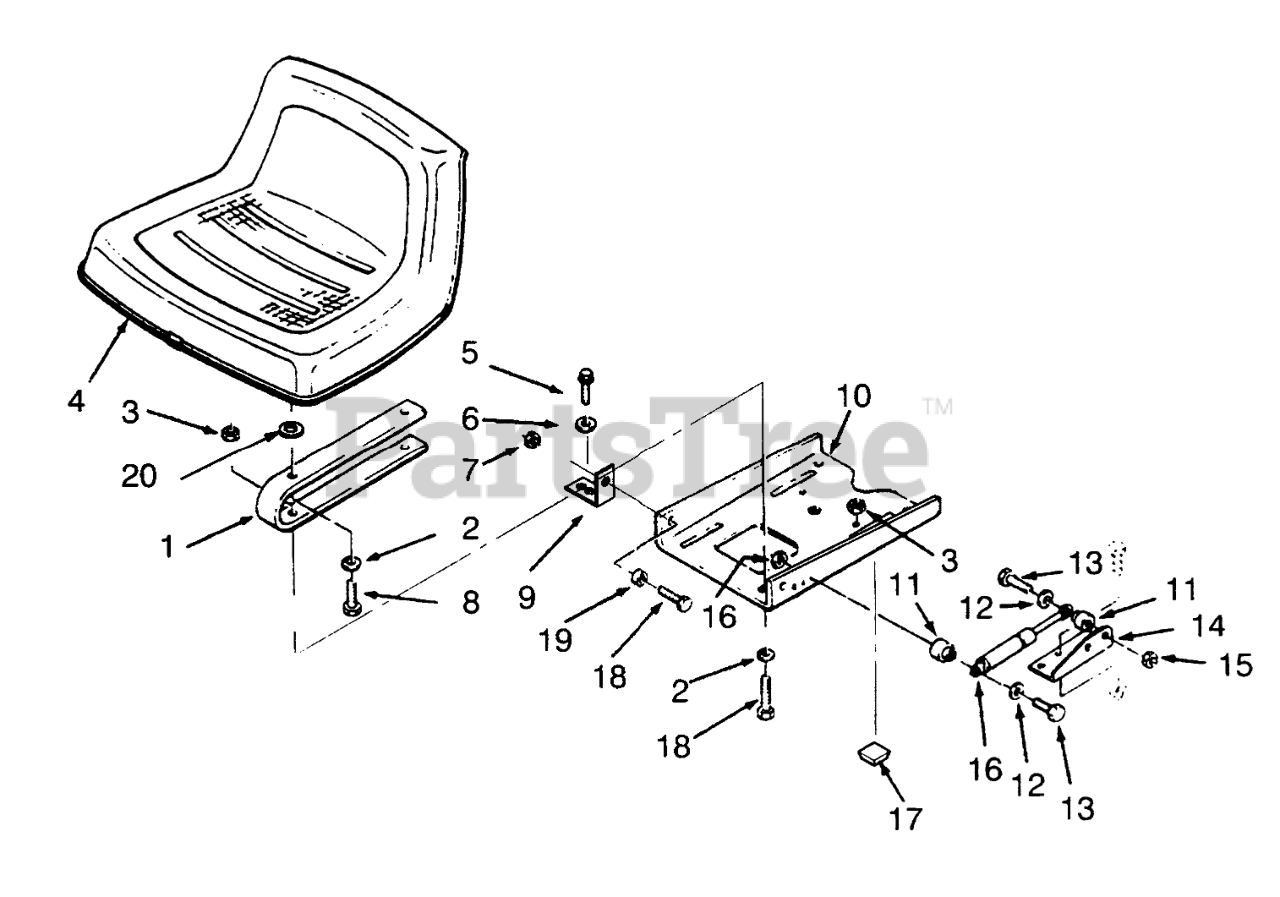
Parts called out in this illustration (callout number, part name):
1	Seat Spring
2	WASHER-LOCK
3	NUT-LOCK, NI
4	SEAT V-510
5	Bolt
6	WASHER-PLAIN
7	NUT-LOCK, NI
8	SCREW-HH
9	BRACKET-PIVOT
10	Plate-SeatPivot
11	SPACER
12	WASHER-FLAT
13	SCREW-HH
14	BRACKET-CYLINDER R
15	NUT-LOCK, NI
16	GAS SPRING
17	BUMPER SJ5514 BLACK
18	SCREW-HH
19	BUSHING
20	SPACER-NYLON
